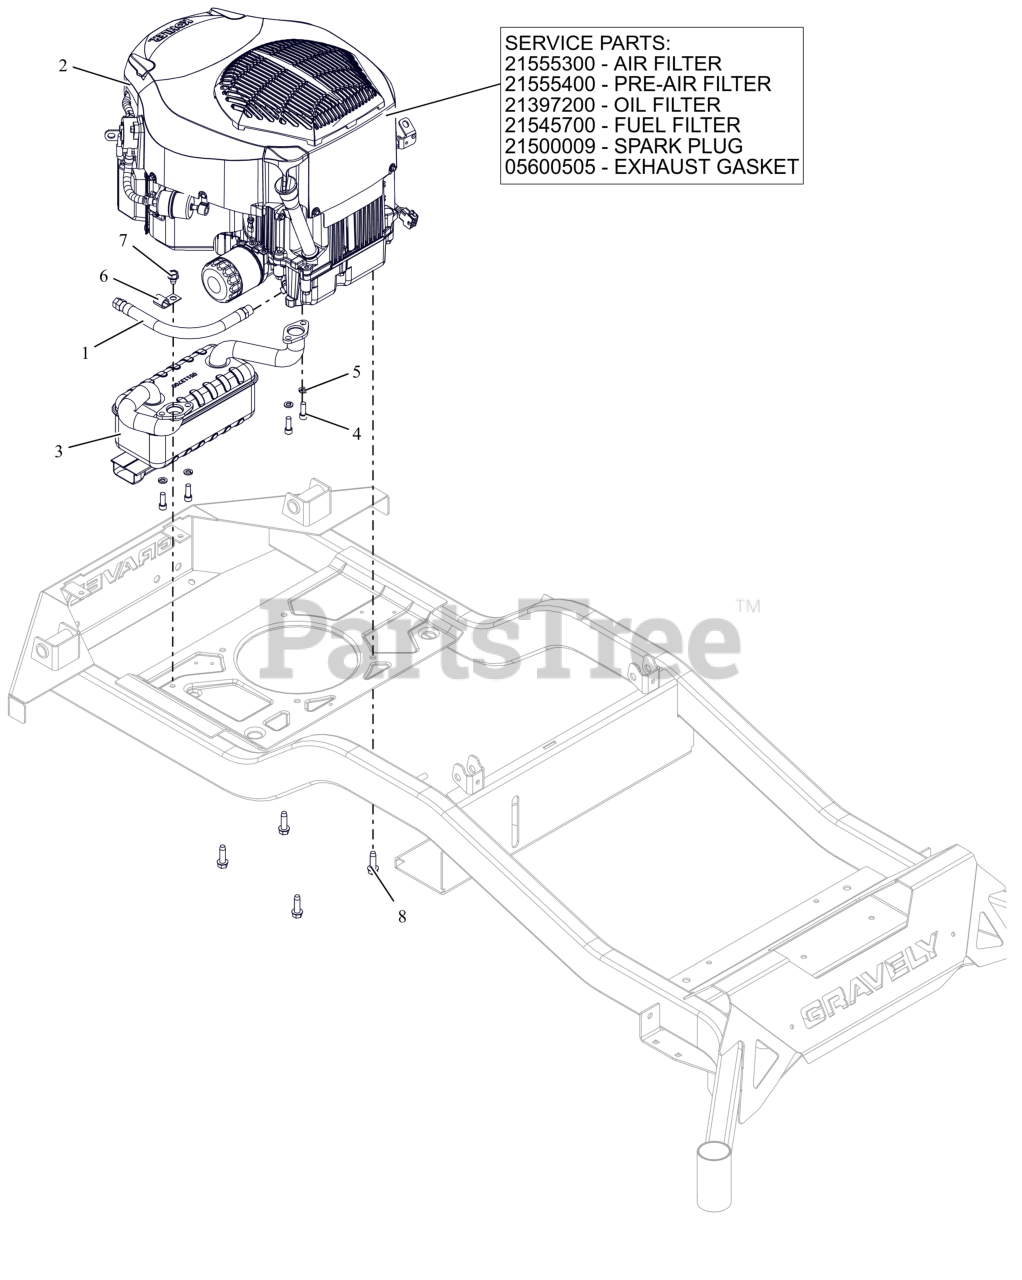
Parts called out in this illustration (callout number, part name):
1	HOSE, OIL DRAIN
2	ENGINE, KOHLER - KT745
3	MUFFLER, KOHLER
4	SCR, SKH .312-18X.875 GR8 ZCC
5	WSHR,LK-REG .312X.078 ZCC
7	SCR,TAP .375-16X.50 HWH TR ZCC
8	SCR,TAP .375-16X1.25HWH TR ZCC
